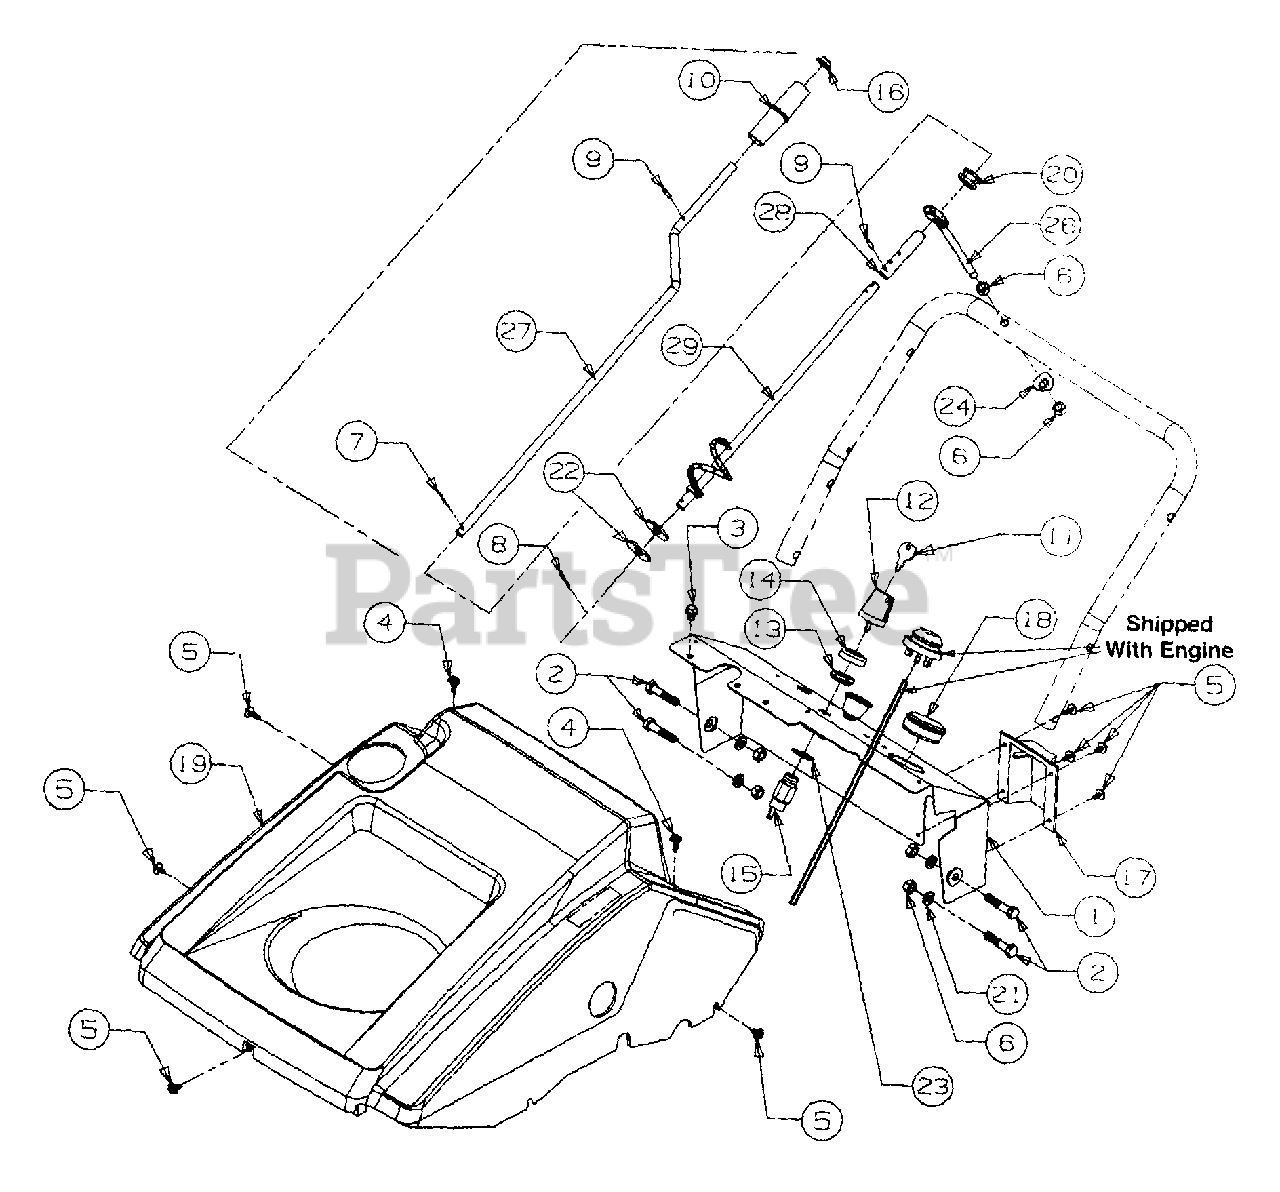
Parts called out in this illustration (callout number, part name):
3	Screw - Hex Washer
4	Screw - Hex
5	Screw - Hex
6	Nut - Hex
7	Hairpin
8	Pin - Cotter
9	Pin - Roll
11	Key - Ignition
12	Key - Ignition with Logo
13	Nut - Ignition Switch
14	Cover - Ignition Switch
15	Switch - Key
16	Cap - Push
17	Cover - Choke
18	Plug - Insert
19	Shroud - Black
20	Grommet - Rubber
21	Washer - Lock
23	Washer - Lock Internal
24	Washer - Saddle
26	Eyebolt - Chute Crank
28	Spacer
